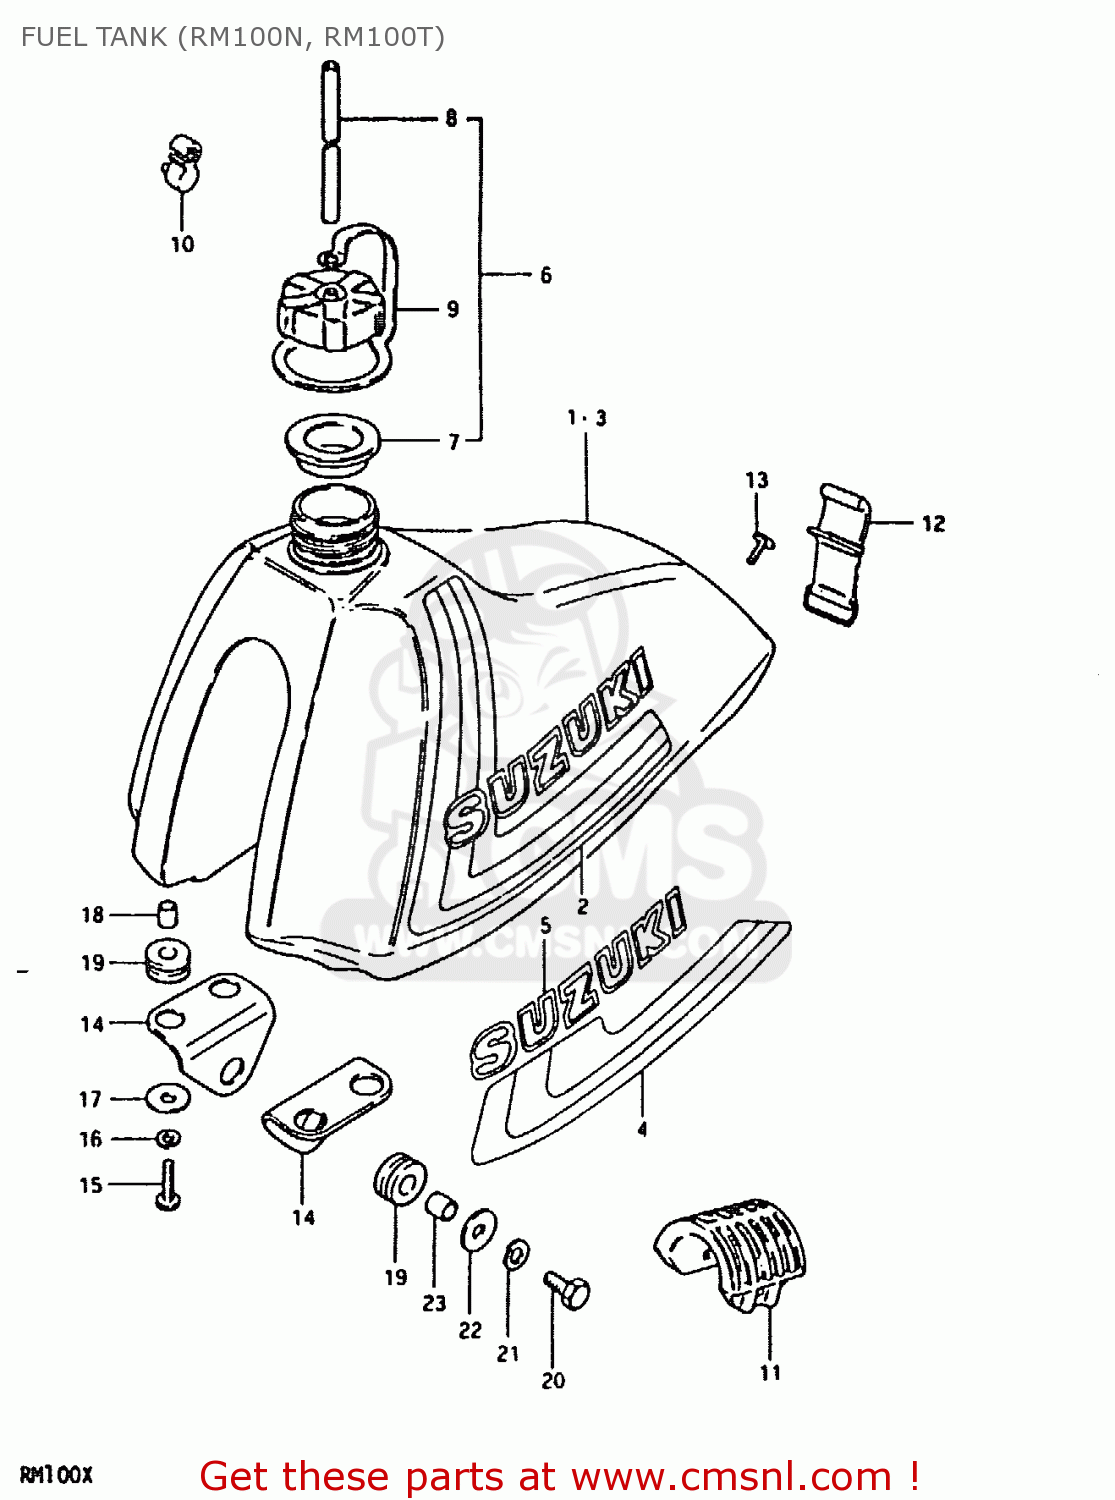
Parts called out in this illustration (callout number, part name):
1	TANK ASSEMBLY,FUEL
2	TAPE SET
3	TANK ASSEMBLY,FUEL
4	TAPE SET,FUEL TANK
5	EMBLEM
6	CAP SET,FUEL TANK
7	GASKET,FUEL TANK CAP (NAS)
8	HOSE
9	BAND,FUEL TANK CAP
10	CLAMP,FUEL TANK BREATHER HOSE
11	CUSHION,FUEL TANK
12	BAND
13	SCREW(6X18)
14	BRACKET,FUEL TANK
15	SCREW
16	LOCK WASHER
17	WASHER (6.5X24X1.6)
18	SPACER(6.8X12X11)
19	CUSHION
20	BOLT
21	LOCK WASHER
22	WASHER (8.2X24X1.6)
23	SPACER (8.8X12X11)
